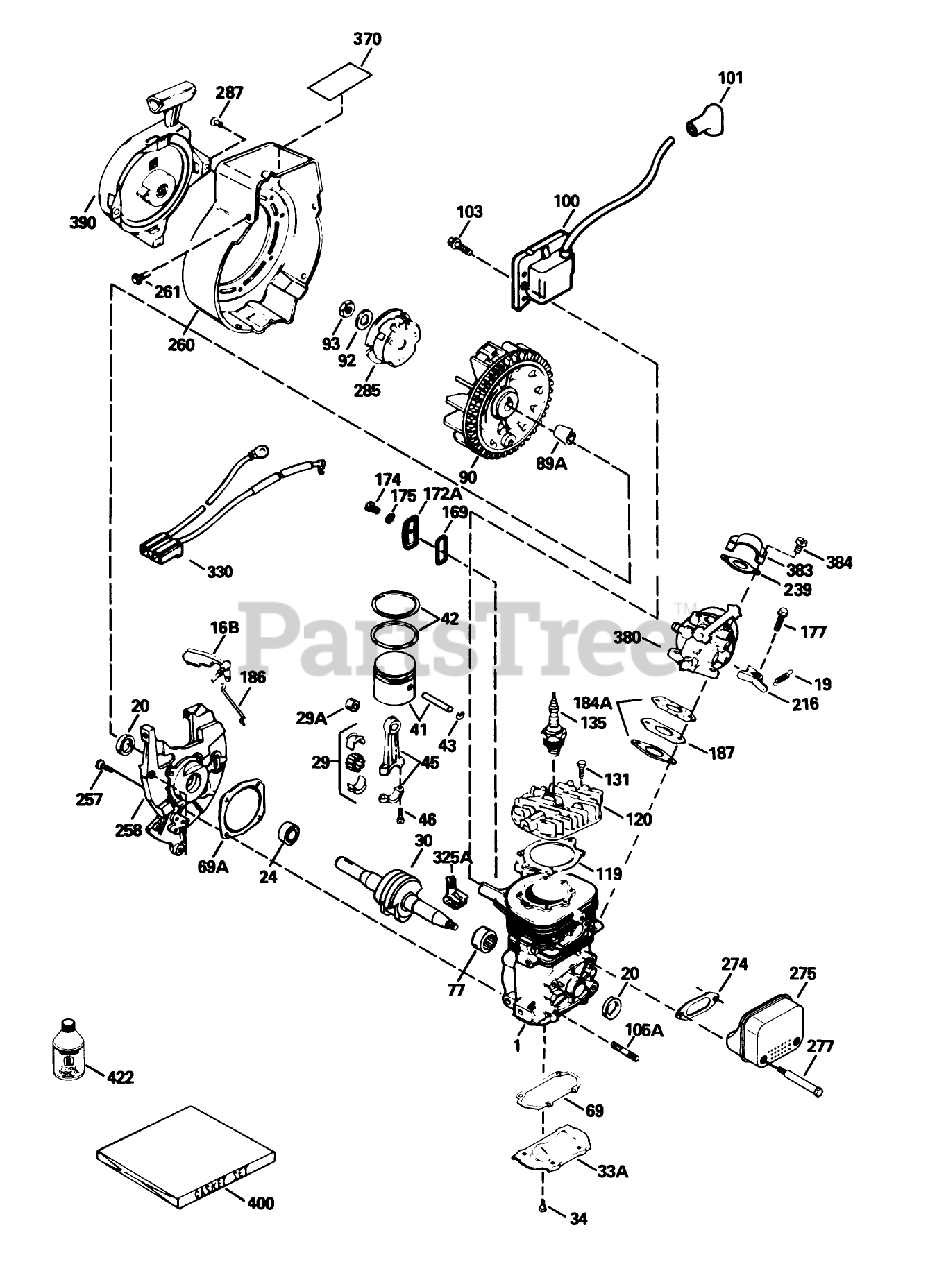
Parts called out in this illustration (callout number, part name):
1	Block Ass-y-Cylinder (Order Short Block if replacement is required.)
16B	Vane-Air
19	Spring-Extention
20	Seal-Oil
24	Bearing-Ball
29	Needle Bearing and Liner Set (37 Needles)
29A	Bearing-Cartridge
30	Crankshaft
33A	Plate-Cover
34	Screw (T-25, 10-24 x 1/2)
41	Piston (Incl. Ref. #43)
42	Ring Set
43	Ring-Retaning
45	Rod Assy.-Connecting (Incl. Ref. #3, 3A 3B)
46	Bolt-Rod, Connecting
69	Gasket-Plate, Cover
69A	Gasket-Cover, Cylinder
77	Bearing-Cartridge
89A	Blade (20 inch)
90	Flywheel
92	Washer-Belleville
93	Nut-Flywheel
100	Solid State
101	Cover-Spark Plug
103	Screw
119	Gasket-Head, Cylinder
120	Head-Cylinder
131	Screw (T-30, 1/4-20 x 3/4)
135	Spark Plug-Resistor (R C J 8Y)
169	Cover-Compression, Release
172A	Comp. Release Cover
174	Screw (T-25, 10-24 x 1/2)
175	Washer
177	Screw (5/32 Allen, 1/4-20 x 1)
184A	Gasket-Carburetor
186	Link-Governor
187	Spacer
216	Lever-Adjusting, Rpm
239	2060A77 WIZARD ROTA
257	Screw (T-30, 1/4-20 x 5/8)
258	Base Assy.-Blower Housing (Incl. Ref. #10)
260	Housing-Blower
261	Screw (1/4-20 x 1/2)
274	Gasket-Exhaust
275	Muffler (Incl. Ref. #274 277)
277	Screw (1/4-20 x 2-3/4)
285	Cup-Starter
287	Rivet-Pop
325A	Clip-Wire
330	Harness-Wire
370	Decal-Warning
380	Carburetor (Incl. Ref. #184A)
383	Baffle-Carburetor
384	Screw
390	Starter-Rewind
400	Gasket Set
422	2-Cycle Oil (8oz)
